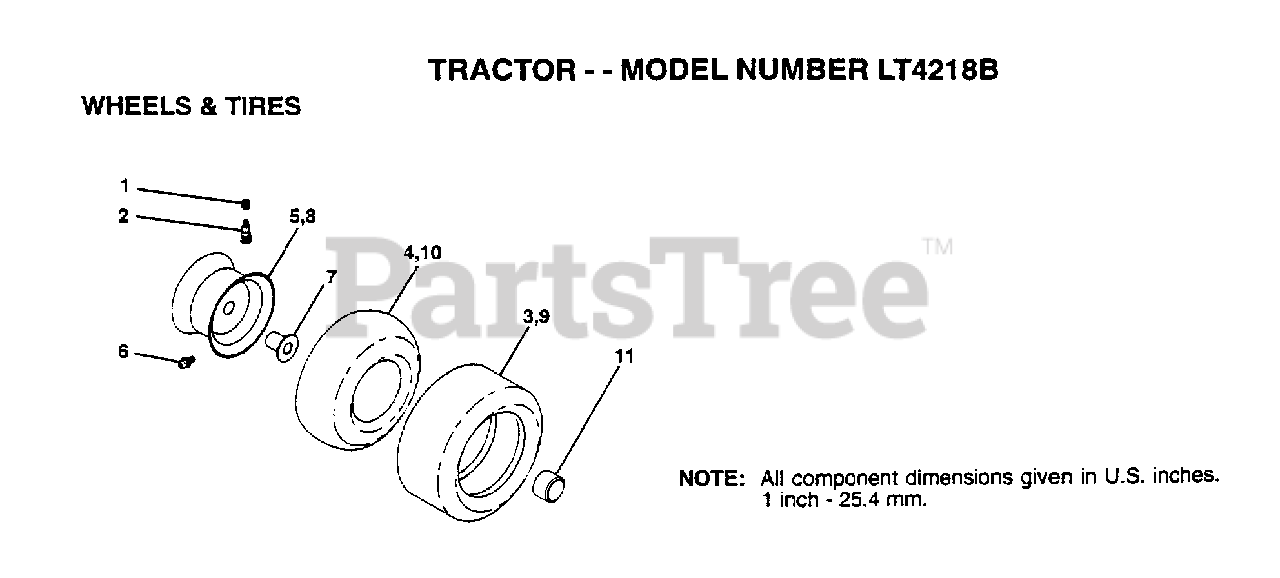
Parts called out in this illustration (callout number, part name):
1	VALVE CAP
2	VALVE STEM LT
4	TUBE.5.3/4.5/6
5	"RIM FRT 6"" ASM"
6	FITTING LT
7	"FLANGE, BEARING"
8	"RIM REAR 8"" ASM"
9	TIRE.20X8-8
10	TUBE.18X9.5-8
11	HUB CAP
